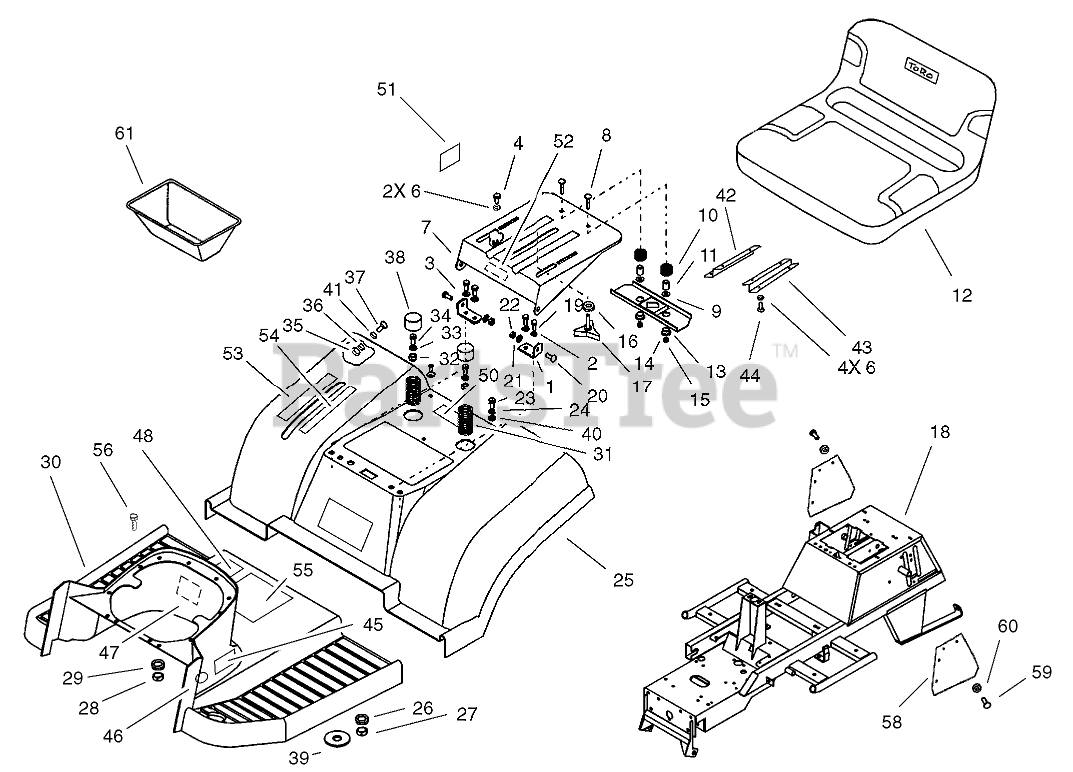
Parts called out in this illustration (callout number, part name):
1	BRACKET-SUPPORT, SEAT
2	WASHER-SPRING
3	SCREW-HH
4	BOLT-HEX
6	WASHER-SPRING
7	SUPPORT-SEAT
8	BOLT-CARRIAGE
9	WASHER-FLAT
10	SPRING-SEAT
11	SPACER-SPLIT
12	SEAT
13	BRACKET
14	BUSHING
15	NUT-LOCK
16	WASHER-SPRING
17	KNOB-ADJUSTMENT
18	FRAME-CHASSIS
19	SCREW-HH
20	SCREW-SUPPORT, SEAT
21	WASHER-PLAIN
22	NUT-LOCK, NI
23	SCREW-HSFH
24	WASHER-FINISH
25	Fender
26	WASHER-FLAT
27	NUT-LOCK, NI
28	NUT-LOCK
29	WASHER-FLAT
30	FOOTREST ASM
31	SPRING-SEAT
32	NUT-LOCK, NI
33	WASHER-PLAIN
34	SCREW-HH
35	NUT-LOCK
36	WASHER-FLAT
37	BOLT-CARRIAGE
38	CAP-HUB
39	WASHER-RUBBER
40	WASHER-RUBBER
41	WASHER-RUBBER
42	BRACKET-RIGHT SEAT
43	BRACKET-LEFT SEAT
44	Screw
45	DECAL - TOWER 170DH
46	DECAL-BRAKE, PARKING
47	DECAL-STARTING
48	DECAL-OPERATION, HYDRO
50	DECAL-BAG TO FRAME
51	DECAL-SWITCH
52	DECAL-DANGER
53	DECAL-HOC, RH
54	DECAL-HOC, LH
55	DECAL-INSTRUCTION
56	SCREW-HH
58	Cover-Rear
60	Washer-Flat
61	Box-Battery
